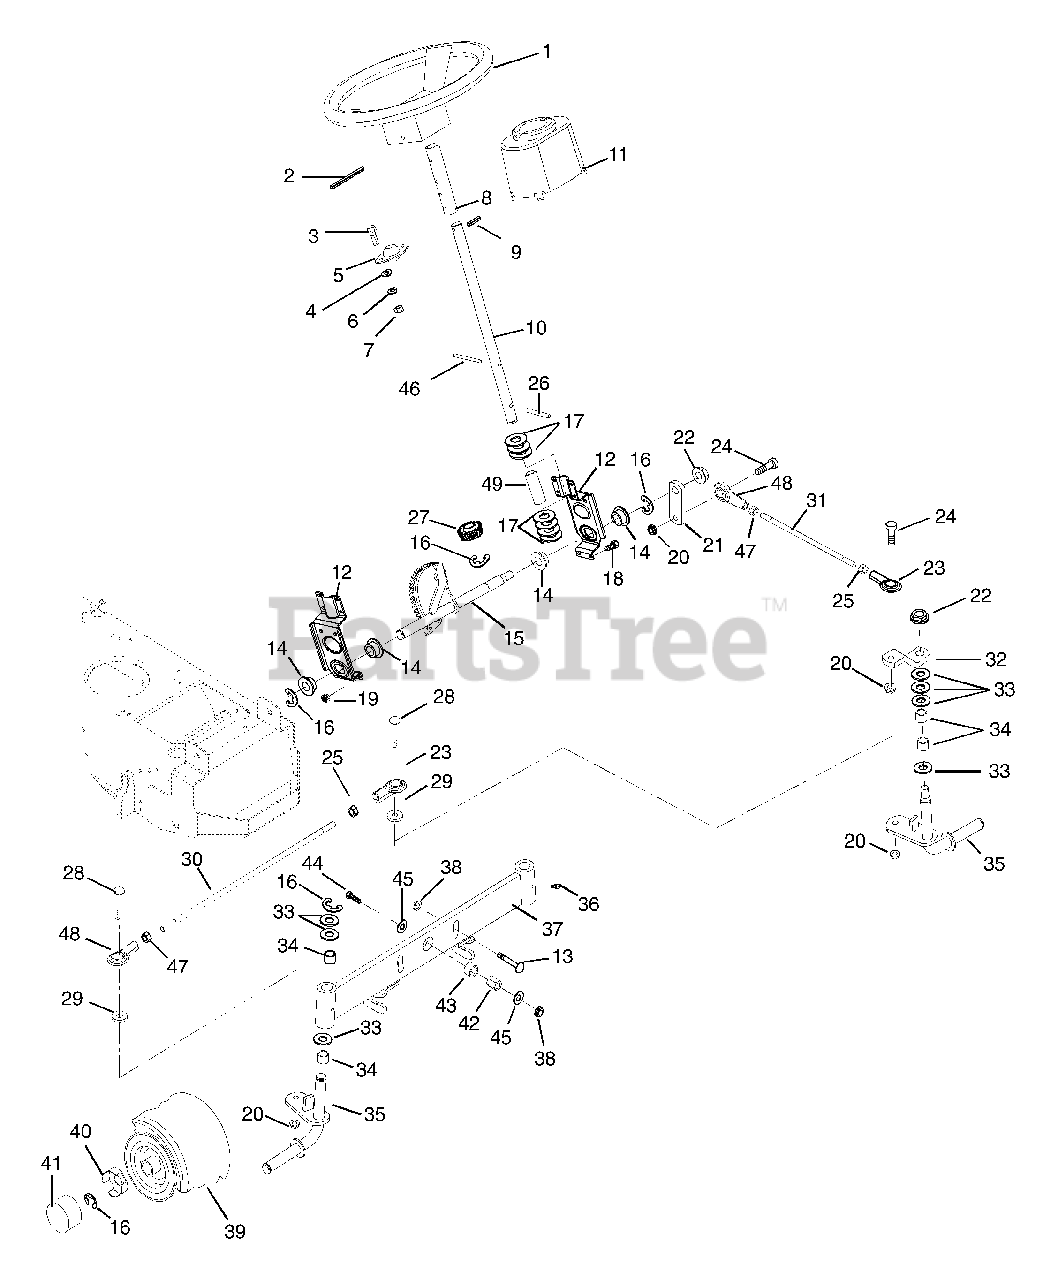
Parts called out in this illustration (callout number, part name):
1	STEERING WHEEL 13"
2	PIN-ROLL .250X1.75
3	@BLT-HEX .31-18X.75 GR5 YWZC
4	@WSHR-FL-STL.312X.734X.065 YWZ
5	BRG-FLG .751X2 HOLESX.81
6	WSHR-LK .312X.097 HVY YWZC
7	@NUT-HEX .31-18 YWZC
8	TUBE .754 X .999 X 5.00
9	PIN-ROLL .250X1.000
10	COLUMN, STEERING
11	CONE- STEERING COLUMN
12	BRACKET-STEERING GEAR
13	@BLT-HEX .38-16X1.50 GR5 YWZC
14	BSHG-FLG .750X1.093X.625X1.375
15	GEAR, STEERING
16	RG-RTNG-EXT .750X.050
17	WSHR-FL-STL.755X1.375X.062YWZC
18	@BLT-HEX .25-20X.75 GR5 YWZC
19	@NUT-LK-CTR .25-20 YWZC
20	@NUT-LK-CTR .38-16 YWZC
21	ARM, STEERING ROD
22	NUT-LK .563-18 GR5 YWZC
23	ROD END, .38 RH
24	BLT-BTHD .38-16X1.25 GR5
25	NUT-JAM .375-24 YWZC
26	PIN .249X1.125 DRIV-LOK SP
27	PINION GEAR-STEERING
28	@BLT-HEX .38-16X1.75 GR5 YWZC
29	BSHG-SLV .377X.624X.370
30	ROD - TIE
31	LINK - DRAG
32	ARM - STEERING SPINDLE
33	WSHR-FL-STL.755X1.375X.062YWZC
34	BSHG-SLV .750X.814X .750 BRZ
35	SPINDLE - LH
35	SPINDLE - RH
36	FTG-LUBE .25-28X.256 YWZC
37	AXLE, FRONT
38	@NUT-LK-CTR .38-16 YWZC
39	TIRE/WHEEL ASSY 15 X6.00-2 PLY
39	WHEEL W/BEARINGS
39	BSHG .75 BORE
39	FTG- LUBE .25-28X.97
39	BRG-BALL .752X1.380X.500
40	SPINDLE CUP
41	HUB CAP
42	BSHG-SLV .377X.623X.775 HEX
43	BSHG-SLV .626X1.000X.524 HEX
44	@BLT-HEX .38-16X1.75 GR5 YWZC
45	WSHR-FL-STL .380X1.50X.125YWZC
46	PIN-ROLL .188X1.13
47	NUT-JAM .375-24 LH YWZC
48	END, ROD-.38 LH
49	BSHG-SLV .753 X 2.00 SELF LUB.
